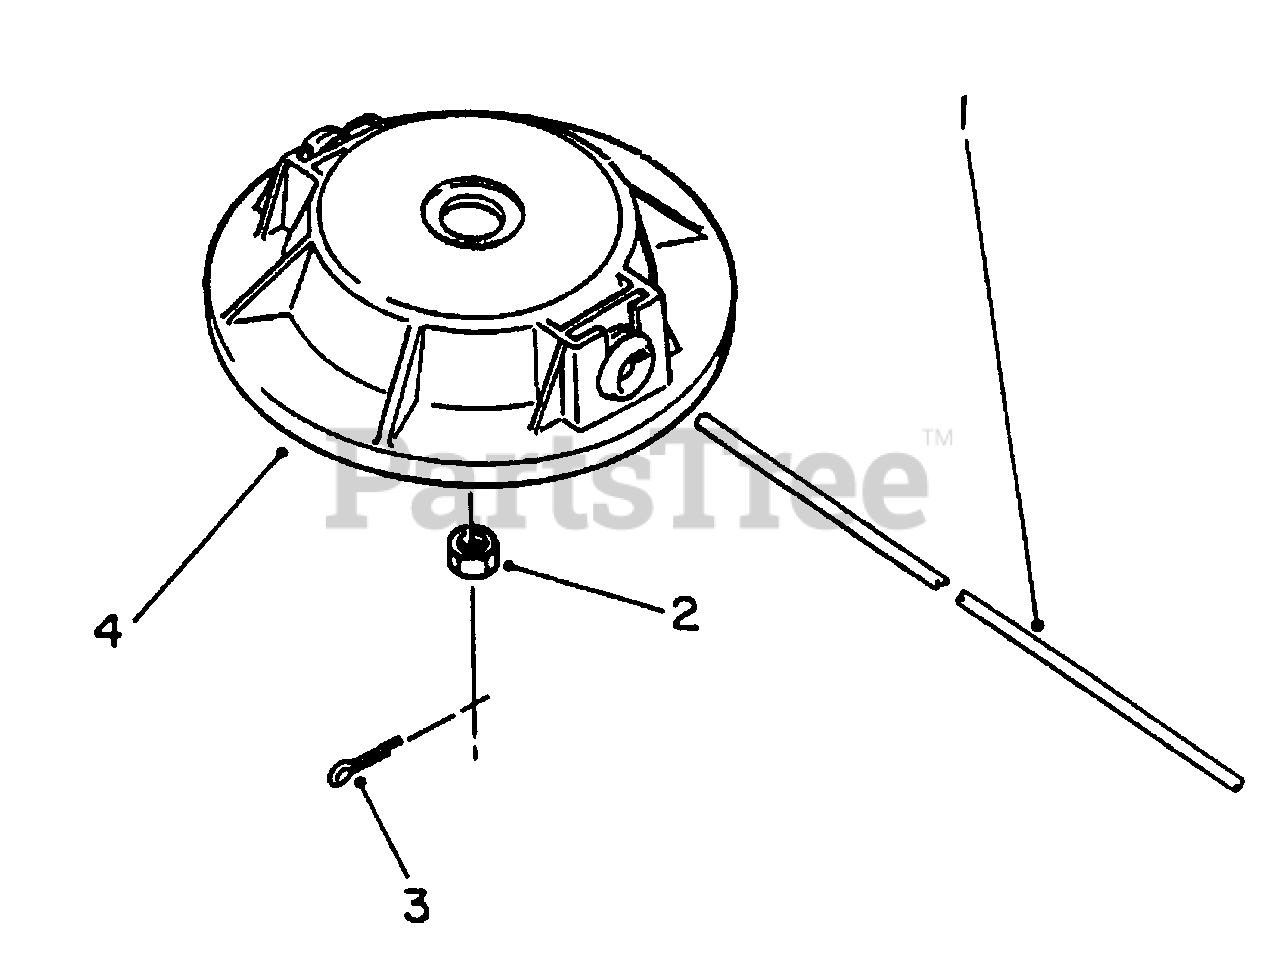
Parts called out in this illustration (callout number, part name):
1	Line-Cutting
2	Nut L.H.
3	Pin-Cotter
4	Cutter Head Assembly
